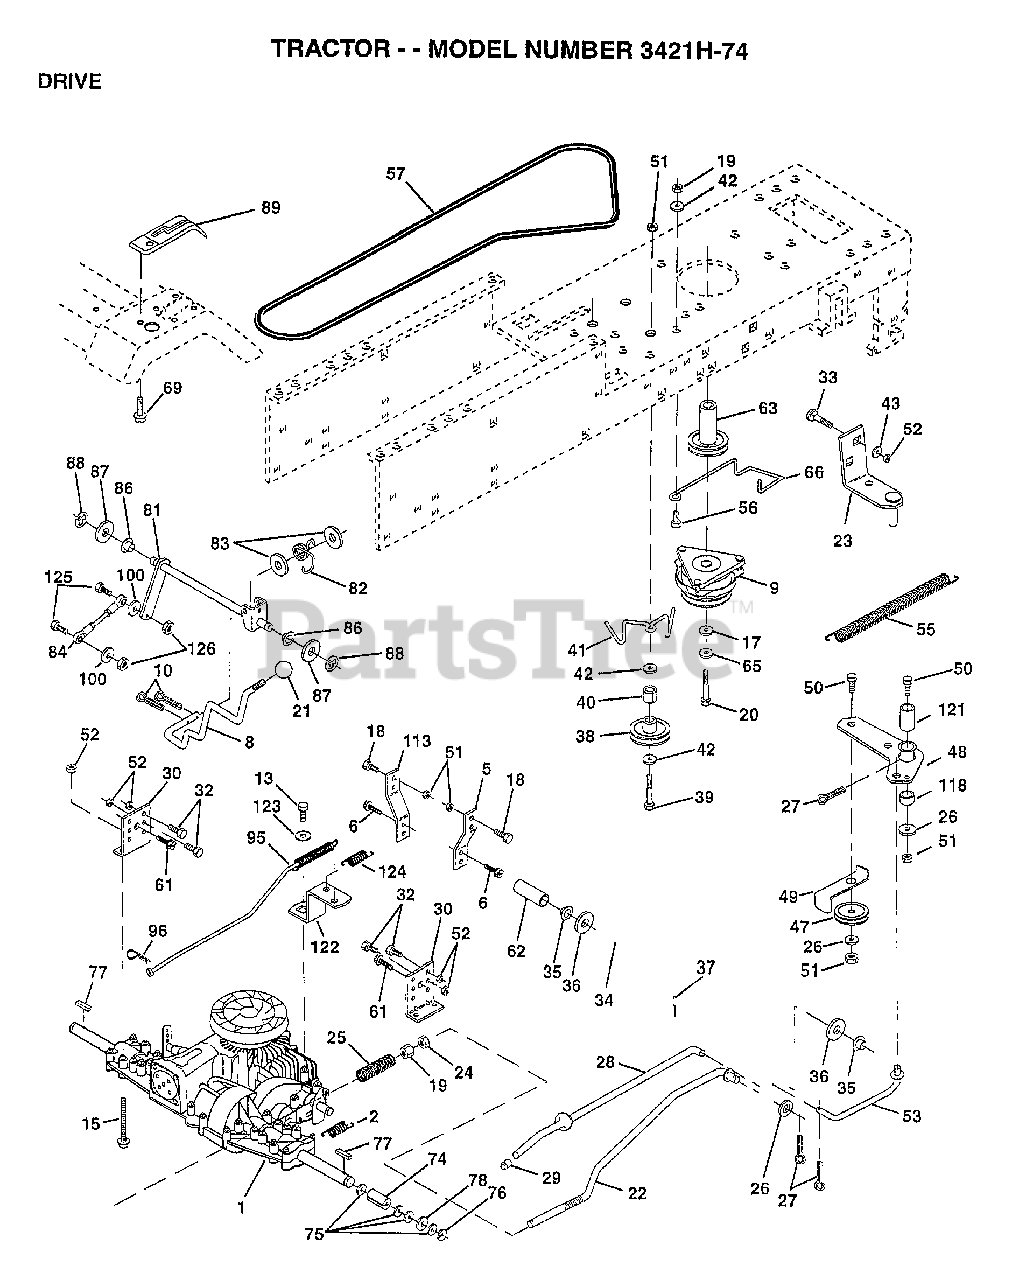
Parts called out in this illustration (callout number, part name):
1	TRANSAXLE, PEERLESS
2	SPRING.BRAKE.RETU
5	STRAP TORQUE
6	SCREW
8	ROD SHIFT FEND LT
10	PIN COTTER 1/8
13	BOLT.1/4-28.W/PAT
15	BOLT.HX.FLG.5/16
17	WASHER
18	BOLT
19	NUT
20	BOLT.7/16-20X4.25
21	KNOB T (1/2-HOLE)
22	BRAKE ROD
23	BRACKET.ASM.MTG
24	NUT
25	SPRING ROD LT
26	WASHER
27	COTTER PIN
28	ROD.BRAKE.PARK.LT
29	PLUNGER CAP T
30	TRANSAXLE MTG BKT
32	BOLT
33	BOLT
34	SHAFT ASM-PEDAL F
35	NYLON BEARING
36	WASHER LT
38	PULLEY.IDLER.FLAT
39	BOLT
40	SPACER T
42	WASHER
43	WASHER T
48	BELLCRANK ASM
49	RETAIN BELT
53	"LINK, CLUTCH T"
55	"SPRING, RETURN LT"
57	"V-BELT,GRD DRIVE"
59	KEEPER BELT CNTSP
61	SCREW
62	PEDAL COVER T
63	PULLEY CLU ELEC
65	LOCKWASHER
66	KEEPER-BELT
69	SCREW HEXWSH H-L
74	"SPACER AXLE,PVST"
75	WASHER
76	E-RING LT
77	SQUARE KEY
78	WASHER
81	SHAFT ASM CROSS
82	"SPRING,TORSION"
83	WASHER
84	"ROD TIE, PVST 20"""
86	BUSHING
87	WASHER D
88	KLIP RING
95	ROAD ASM BYPASS
96	RETAINER M
100	WASHER M
113	"STRAP,TORQUE"
118	SPACER-BELLCRANK
121	NYLINER-CLUTCHING
122	"PLATE-BYPASS,PVST"
124	SPRING RETURN
